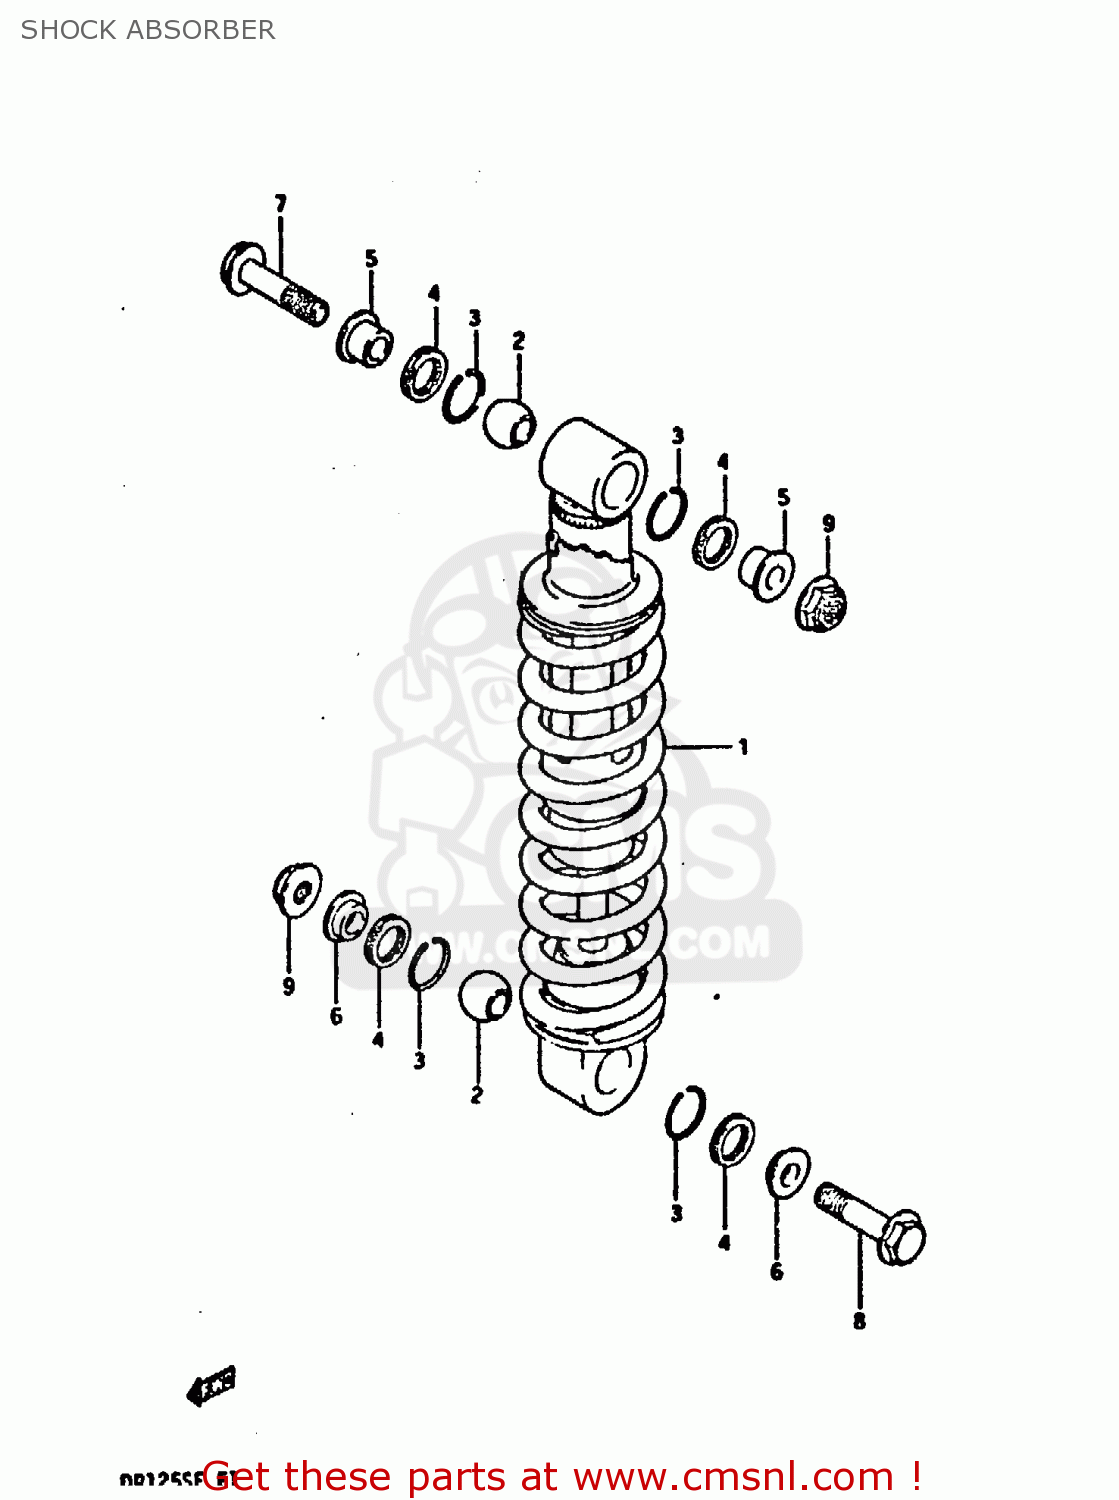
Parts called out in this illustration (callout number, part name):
1	ABSORBER ASSEMBLY,REAR SHOCK
2	BEARING,REAR SHOCK ABSORBER
3	RING
4	DUST SEAL
5	COLLAR,UPR
6	COLLAR,LWR
7	BOLT(10X60)
8	BOLT(10X50)
9	NUT
